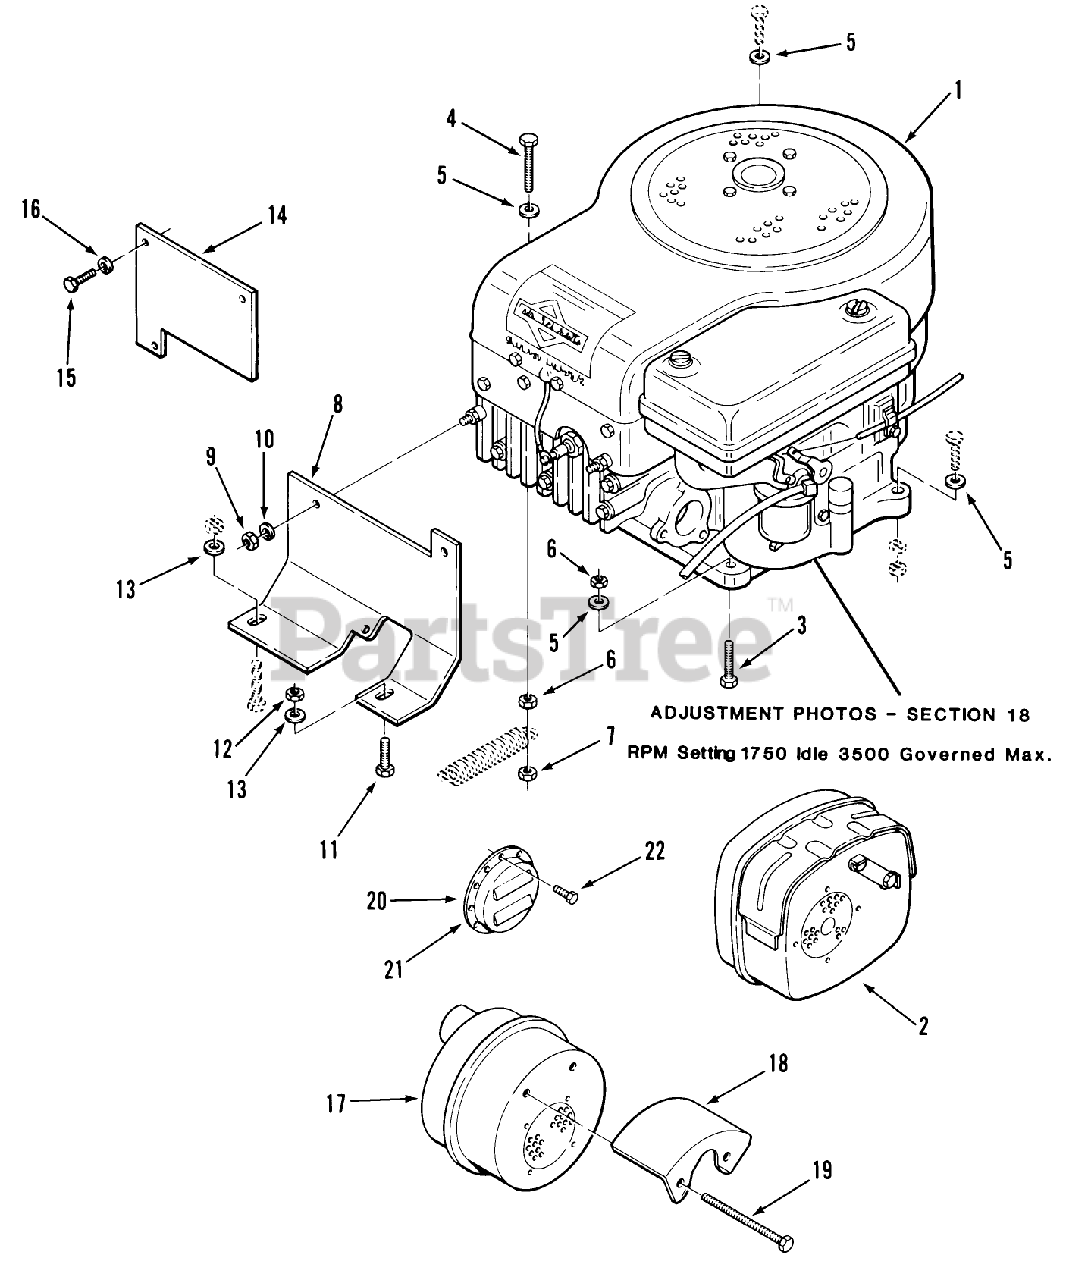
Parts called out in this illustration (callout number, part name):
1	Engine-08 HP BS Model 190707 Type 2167-01 A-85 ONLY
1	Engine-11 HP BS Model 252707 Type 0682-01 A-115 ONLY
2	Muffler A-85 ONLY
5	WASHER 5/16 SAE
10	Lockwasher
20	*Louvered Deflector A-115 ONLY
21	*Louvered Deflector A-85 ONLY
22	*Screw
